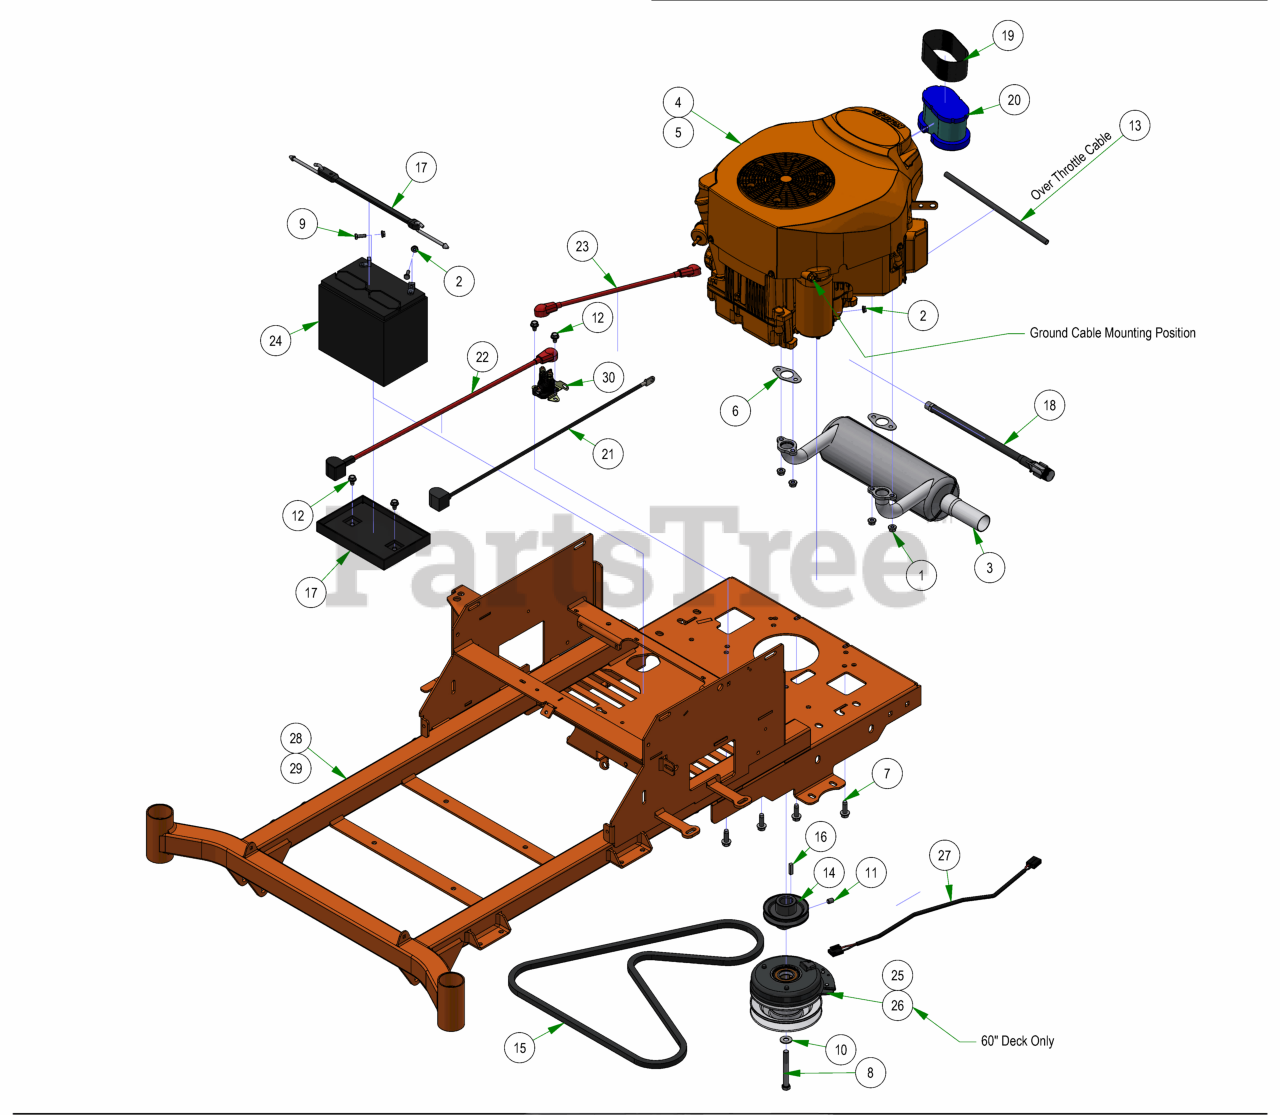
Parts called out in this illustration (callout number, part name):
1	M8 Nut Connects the 015-1012-00 and the 015-8240-00
2	1/4-20 HEX SERRATED FLANGE NUT HARD/ZINC
3	Kohler Muffler
4	KT726-3013 Kohler Engine 1" Shaft
5	Kohler KT722 Engine
6	Exhaust Gasket
7	3/8-16 X 1-1/8 HEX WASHER UNSLOT SERRATED (TRI-LOB) TRS ZINC YELLOW
8	7/16-20 x 3 1/2" Hex Bolt GR8 W/ Patch
9	1/4-20 X 3/4 HEX CAP SCREW (GR.5) ZINC
10	3/8 FLAT WASHER USS (1" OD) ZINC
11	3/8-16 X 1/2 SOCKET SET SCREW (CUP PT) PLAIN
12	5/16-18 X 1/2 HWH unslot (F) tcs zinc
13	Braided Heat Shielding, 12"
14	3-3/4" Motor Pulley
16	1/4 X 1 SQ MACHINERY KEY 1018 STL PLN
17	2023 Battery Hold Down Assembly
18	Kohler Oil Drain
19	25/26 HP Koh Precleaner ZT/MZ
20	25/26 HP Koh Air Filter ZT/MZ
21	24 inch Black Cable – MZ/ZT
22	24" Red Battery Cable
23	14" Red Battery Cable
24	SP-35 Battery
25	105 Ft Lb. Clutch - 1" Shaft
26	120 Ft Lb. Clutch - 1" Shaft
27	Clutch Pigtail
28	2025 MZ 42-48 Frame
29	2025 MZ-Avenger 54-60 Frame
